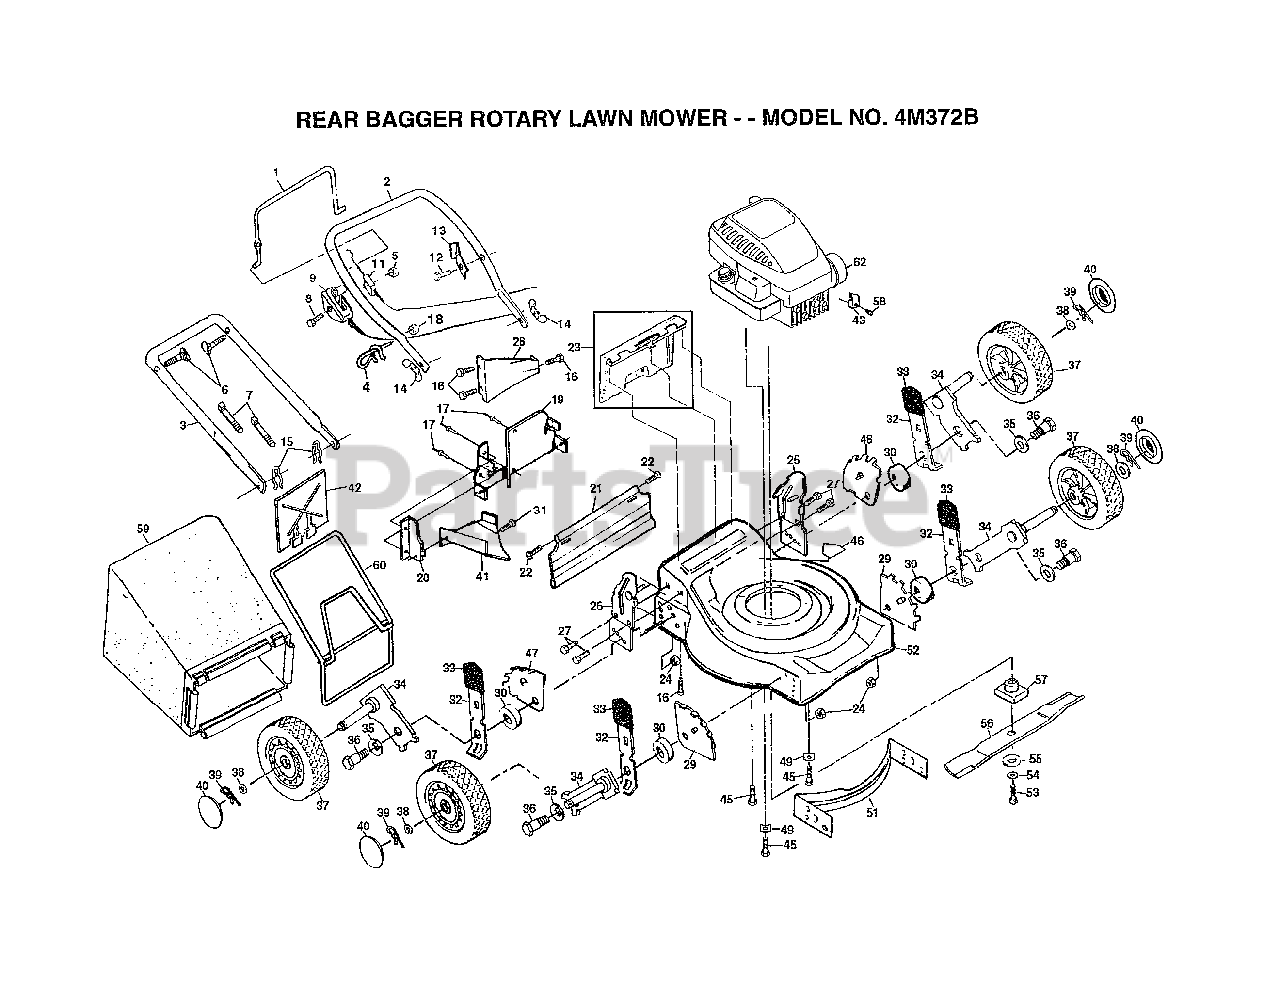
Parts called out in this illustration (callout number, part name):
1	CONTROL BAR
4	ROPE GUIDE
6	BOLT.HANDLE.LM
8	SCREW.HXHD.WASH.
9	"CONTROL, THROTTLE"
11	"CABLE,ENG ZONE CO"
12	TAPPING SCREW
13	"BRKT,UPSTOP"
14	"NUT,WING PM"
15	HAIRPIN COTTER
16	SCREW
17	BLIND RIVET
18	NUT
19	PLATE.BACK
21	SKIRT.REAR.FGD.22
22	HINGE SCREW
23	KIT.DOOR.REAR.22
24	LOCKNUT PM
27	SCREW
28	REAR BAFFLE
29	BRACKET.ADJ.9POS.
31	SCREW PM
32	SPRING SELECTOR
33	KNOB PM
34	ARM.AXLE.ASM.BZP.
35	"WASHER, BELLEVIL."
36	BOLT SHLD 3/8-16
37	WHEEL.8X1.75.WHT
39	HEX FLANGE LOCKNT
40	HUB CAP
41	DISCHARGE BAFFLE
42	MULCHER PLATE
43	CABLE CLAMP
45	SCREW
46	DECAL HYT
47	BRACKET.ADJ.9.RH
48	BRACKET.ADJ.9.LH
52	KIT.HSG.22RD.PUSH
53	SCREW
54	LOCKWASHER
55	"WASHER,HARDEN"
56	"BLADE.MULCH.22"""
57	ADAPTOR.BLADE.LM
58	SCREW PM
59	GRASSBAG.250B1.BL
60	FRAME.CATCHER.2.5
